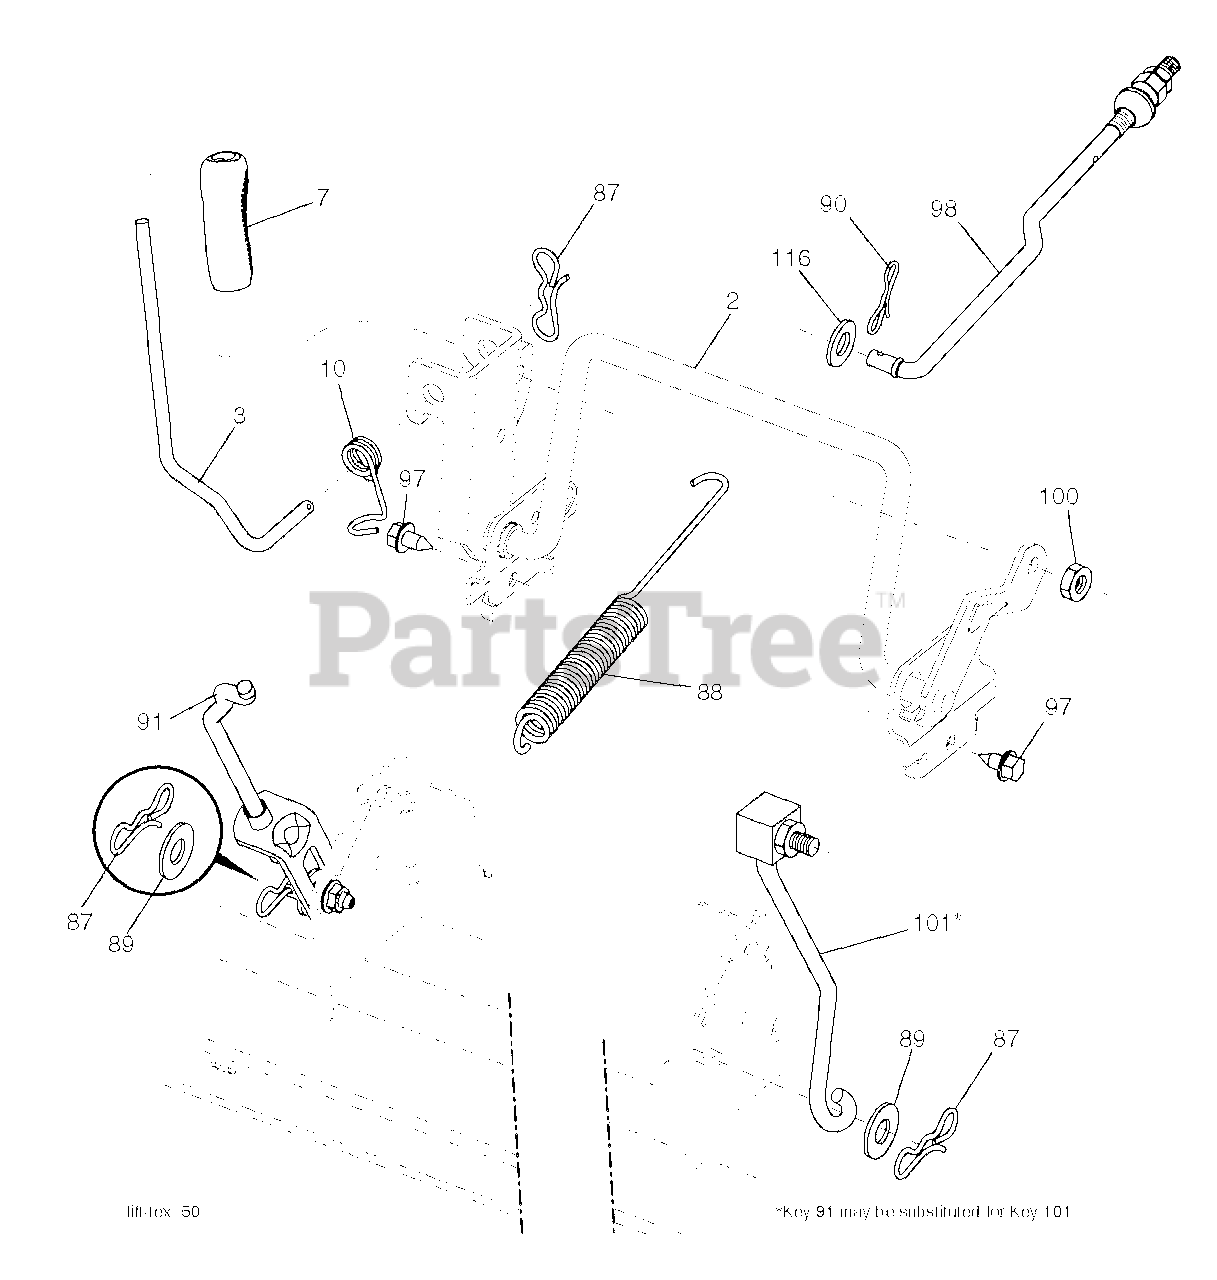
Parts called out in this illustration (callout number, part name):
2	SHAFT LIFT DECK WELD
3	LEVER.LIFT.HANDLE.LT
7	GRIP.HANDLE.LIFT.PVC.BLACK
10	SPRING.TORSION.LIFT.HANDLE
87	PIN.COTTER.7/16.BOW TI.
88	SPRING.DK.LIFT.97/107.TXCRDII
89	WASHER.CLEAR.ZINC
90	PIN.COTTER.5/16.BOW TI
91	LINK.ASM.LIFT.REAR
98	LINK.ASM.SUSP.FRONT.MW
100	LOCKNUT
101	LINK.ASM.LIFT.FIXE.38/42/46"
